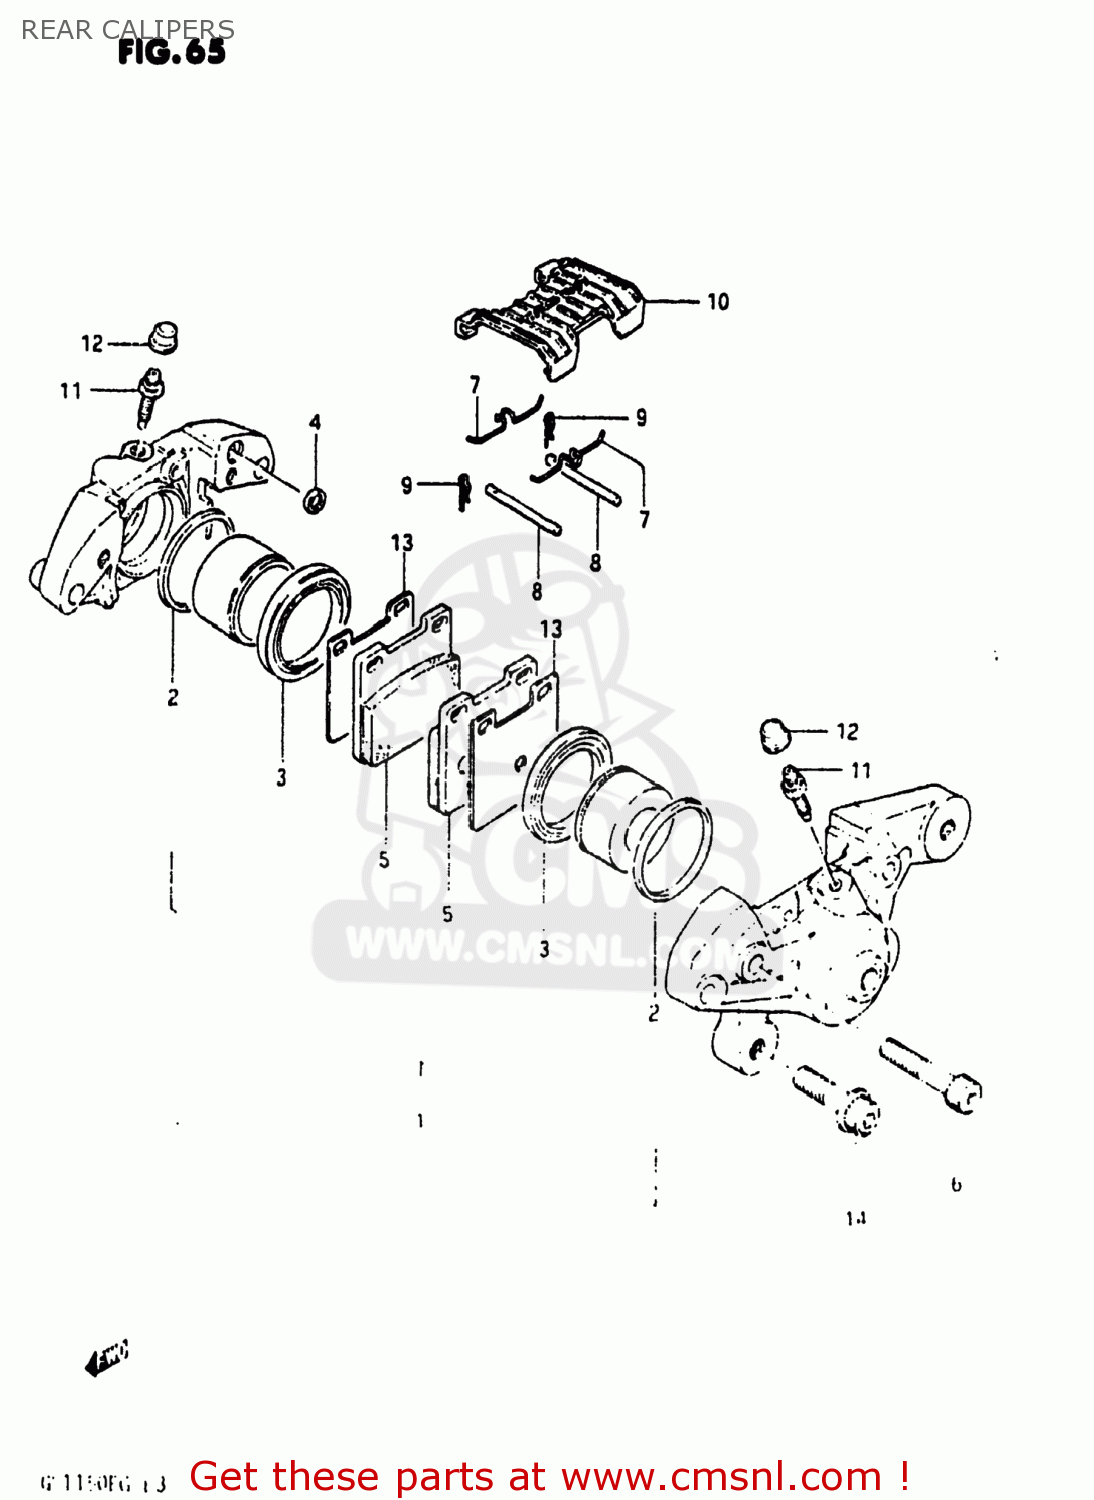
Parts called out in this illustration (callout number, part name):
1	PISTON SET
2	SEAL,PISTON
3	BOOT,PISTON
4	SEAL,JOINT
5	PAD,BRAKE
6	BOLT,CALIPER
7	SPRING
8	PIN,PAD
9	CLIP,PAD PIN
10	COVER,CALIPER
11	BLEEDER
12	CAP,BREATHER
13	SHIM,PAD
14	BOLT 10X28
